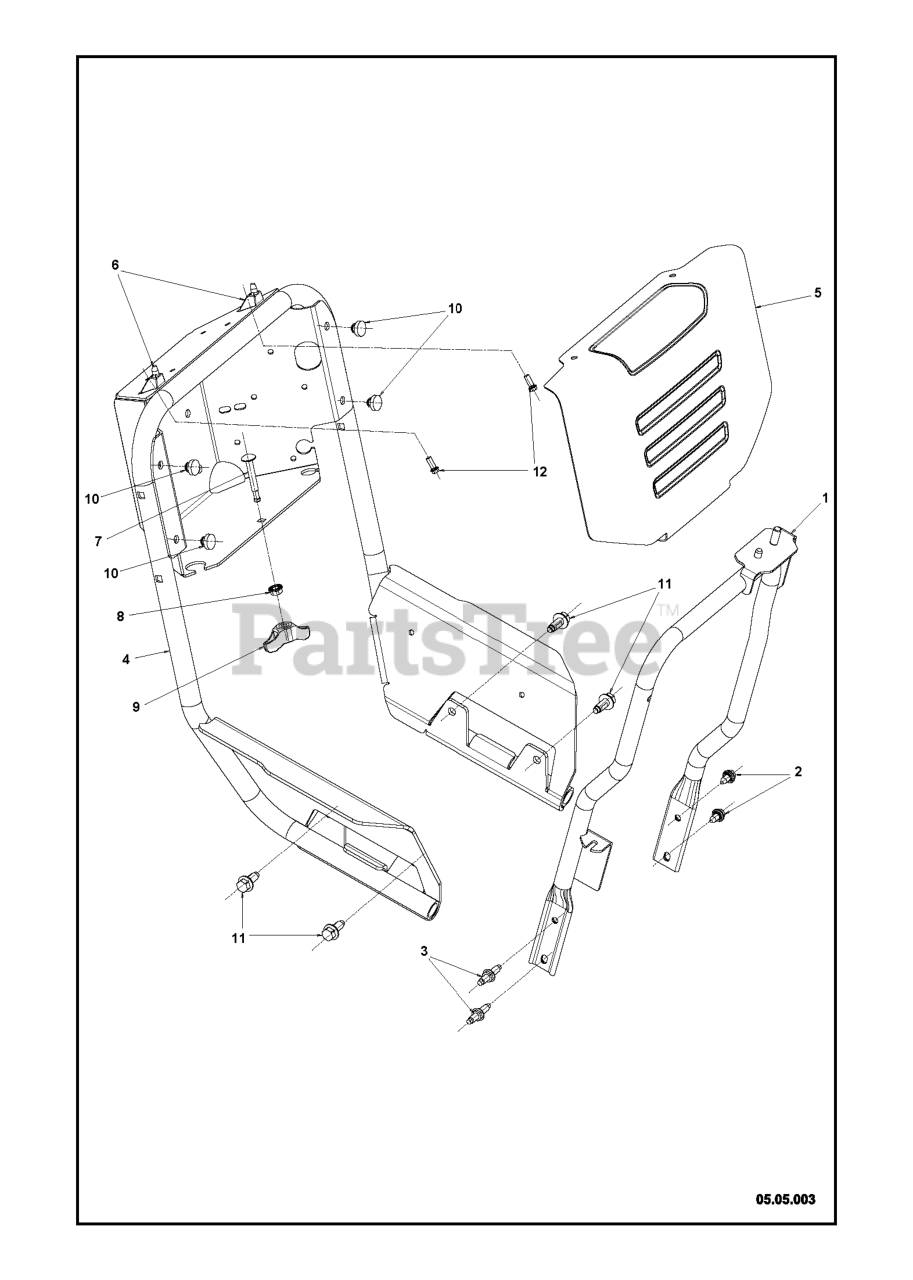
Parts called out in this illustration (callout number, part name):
1	SUPPORT WELDMENT, CHUTE PAINTE
2	BOLT.5/16HEX.WHS.HD
3	STUD BOLTED HEX HEAD
7	BOLT.HAND.PIV.ADJ.313-18.21EFF
8	GSPW Hardware
10	GROMMET.BUMPER
11	SCREW HEXAGON HEAD FLANGE 3/8-
12	SCREW.HWH.13-16-5.8.BZP
